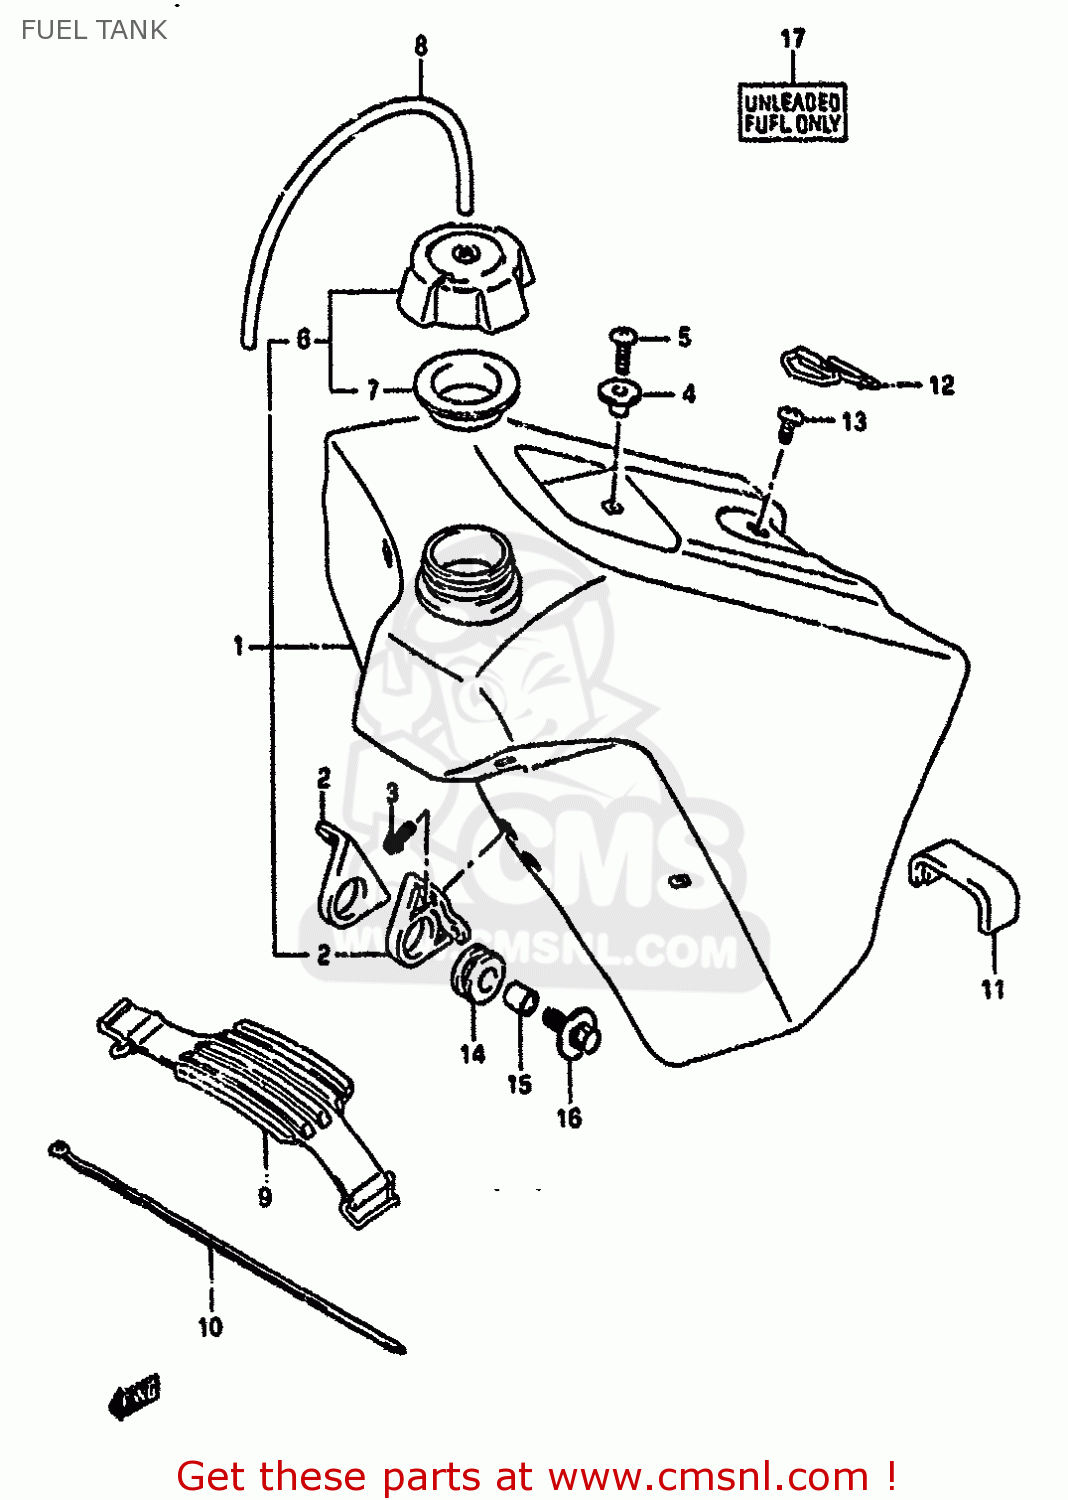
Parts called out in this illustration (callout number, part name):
1	TANK ASSEMBLY,FUEL
2	BRACKET,FUEL TANK FR
3	BOLT
4	HOOK,SEAT,FRONT
5	SCREW
6	CAP SET,FUEL TANK
7	GASKET,CAP (NAS)
8	HOSE
9	CUSHION,FUEL TANK NO.1
10	CLAMP
11	CUSHION,FUEL TANK,UPPER
12	BAND,FUEL TANK RR
13	SCREW
14	CUSHION
15	BOLT(8X30)
16	SPACER (8.8X12X13.5)
17	LABEL,UNLEADED FUEL
